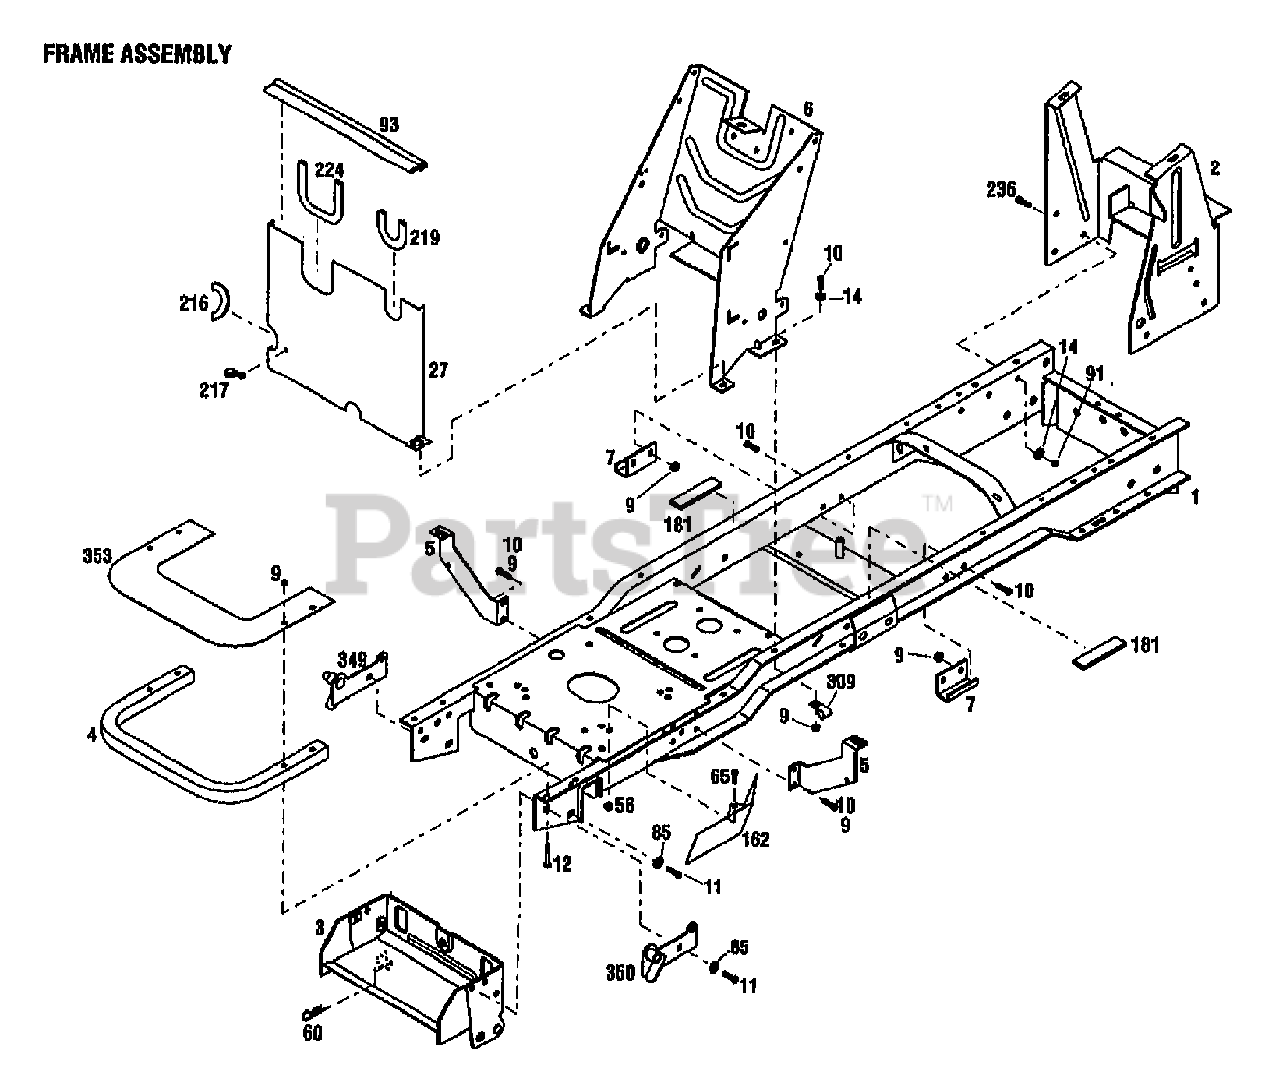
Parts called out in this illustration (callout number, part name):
1	ASSM-FRAME {13078}
1	ASSM-FRAME LTX {13079}
2	SUPPORT-REAR TANK
3	ASSM-BRKT ATTACHMENT
4	BUMPER-FRONT
5	SUPPORT-FENDER
6	SUPPORT-CONSOLE
7	STOP-MOWER DECK {13078}
9	NUT-HFLK 5/16-18 ZP
10	SCR-HHC 5/16-18X.75 GR 5 ZP
11	SCR-HH 3/8-16X1.0 G5 ZP
12	SCR-HH 5/16-18X1.75
14	WASHER-FLAT 5/16 SAE
27	SHIELD-HEAT {13078}
56	NUT-HF/LK 1/4-20 ZP
60	PIN-HITCH .125X2.56 ZP
65	SCR-HH 1/4-20X.625
85	WASHER-FLAT 3/8 SAE
91	NUT-TOP/LK 5/16-18 ZP
93	GASKET-HEAT SHIELD {13078}
162	SHIELD-HEAT UPPER
216	TRIM {13078}
217	HANGER-CABLE {13078}
219	TRIM {13078}
224	TRIM-HEAT SHIELD {13078}
236	SCR-HFLK 5/16-18X.75 ZP
309	CLIP-J
349	PLATE-PIVOT RH
350	PLATE-PIVOT LH
353	SHIELD-HEAT
